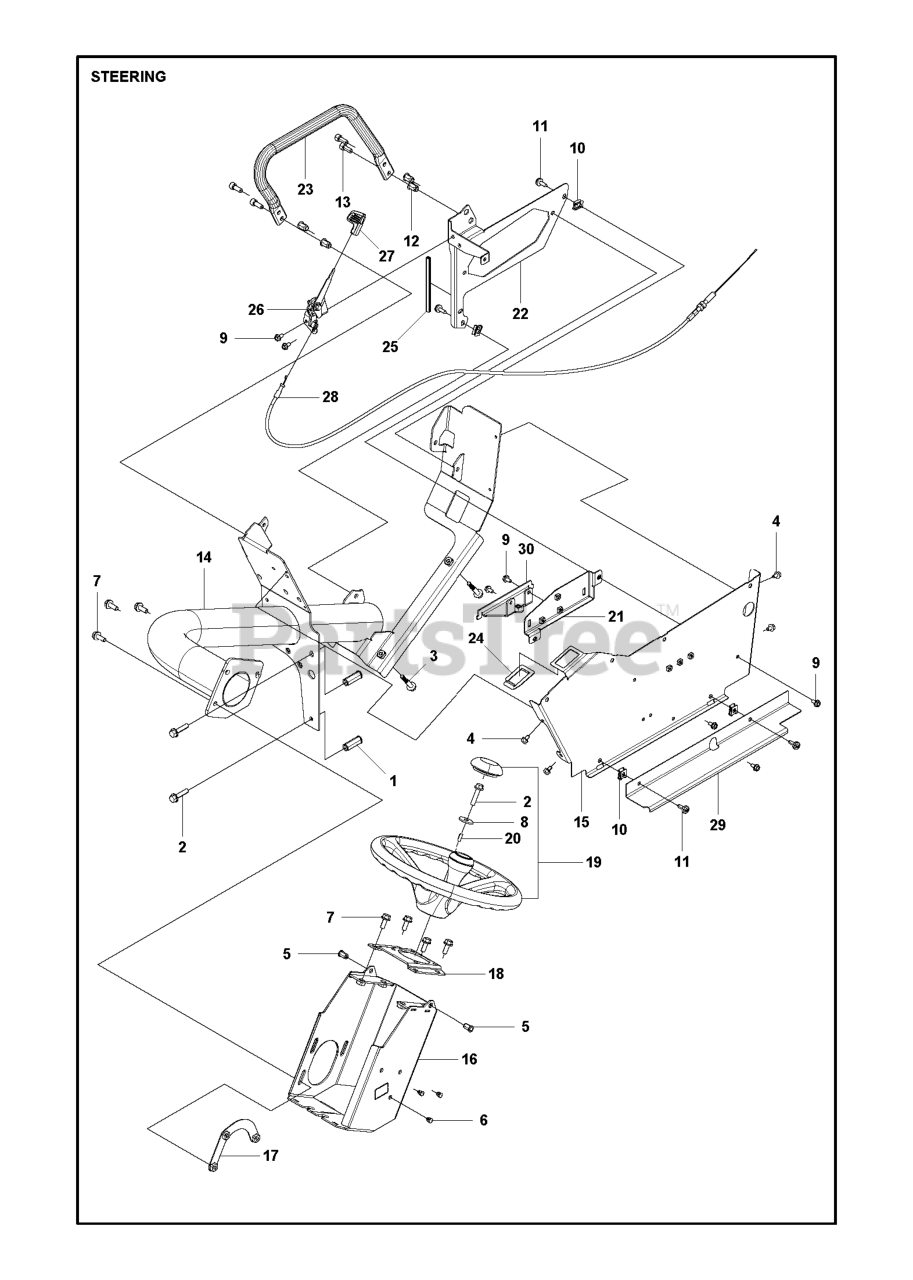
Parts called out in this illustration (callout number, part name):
2	SCREW EHHFM
9	SCREW EHHFM
16	BRACKET ASSY STEERING COLUMN P
